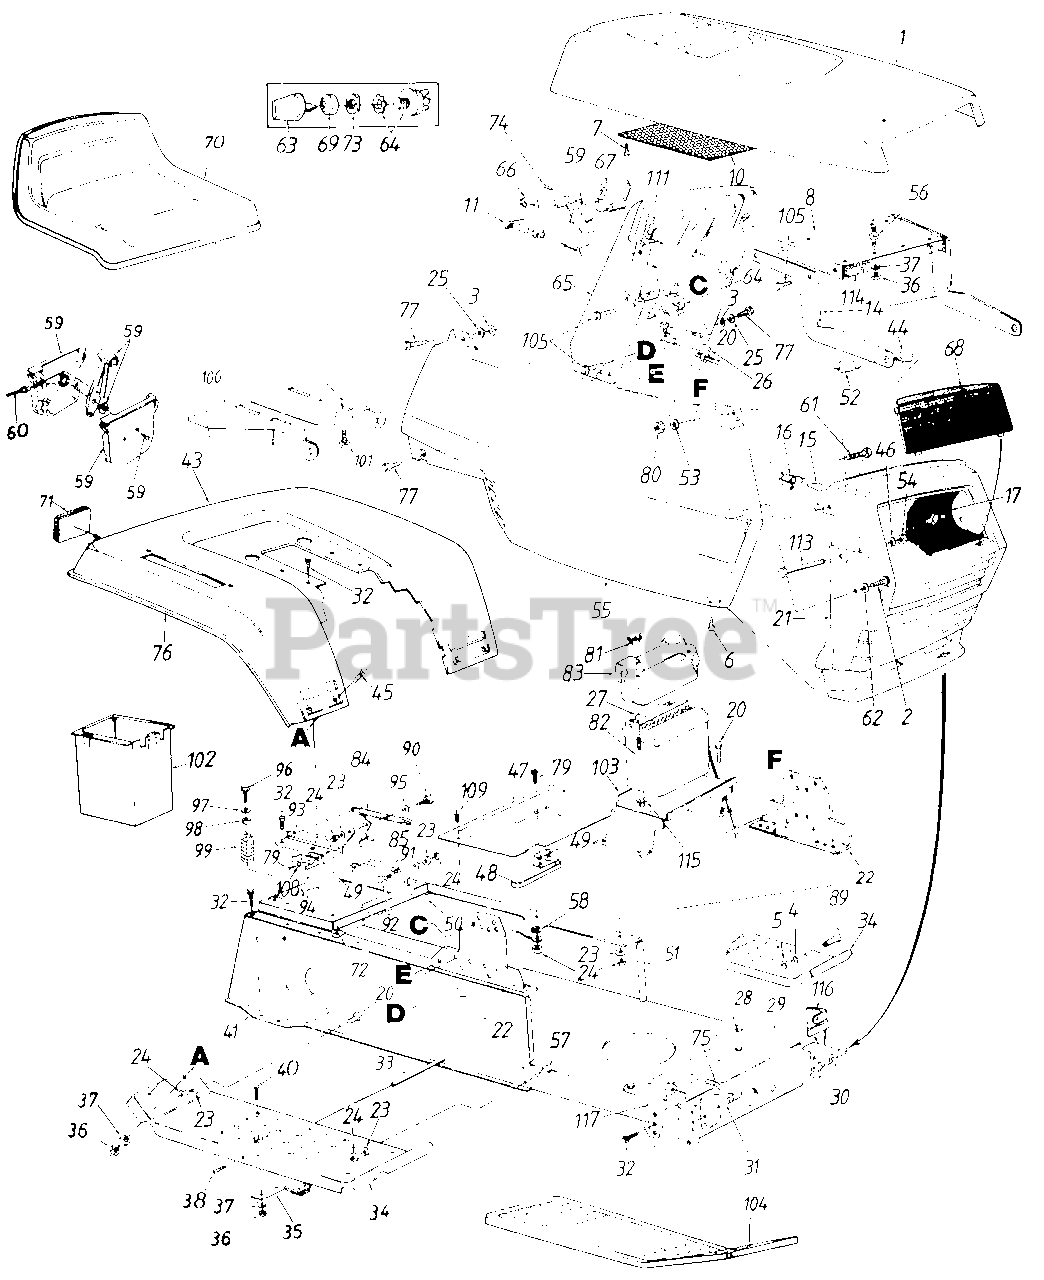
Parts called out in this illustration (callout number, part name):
3	Bolt Retainer 1/4" I.D.
4	L-Wash. 3/8" I.D.
5	Hex Nut 3/8-16 Thd.
6	Truss Mach. AB-Tap Scr. #10 x .5" Lg.
7	Hex Wash Hd. AB-Tap Scr. #8 x .5" Lg.
8	Hood Plate
11	Choke Control 29" Lg.
14	Hood Hinge
15	Lamp
16	Twist Lock-Lamp Socket
17	Reflector-Headlight
20	Hex Bolt 5/16-18 x .75" Lg.
21	Grille
22	Dash Support Bracket
23	L-Wash. 5/16" I.D.
24	Hex Nut 5/16-18 Thd.
25	Fl-Wash. 1/4 I.D. x.93" O.D.
26	Cable Tie
27	12 Volt Battery
28	Lower Frame
29	Front Pivot Brk't.
30	Grille Mount Brk't.-L.H.
31	Grille Mount Brk't.-R.H.
32	Hex Wash. Hd. AB-Tap Scr. 5/16 x .75" Lg.
33	Running Board Rod
34	Running Board
35	Blade Brake Ass'y.
36	Hex Nut 1/4-20 Thd.
37	L-Wash. 1/4" I.D.
38	Truss Mach. Scr. 5/16-18 x .75" Lg.
40	Carr. Bolt 1/4-20 x .62"
45	Carriage Bolt 1/4-20 x .50" Lg.
46	Fl-Wash. .328" I.D. x .68" O.D.
47	Transmission Panel
48	Reverse Safety Switch
49	Insulator Nut Plate
50	Hitch Plate
53	Fl-Wash. .281" I.D. x .5" O.D.
54	Hex Cent. L-Nut 5/16-18 Thd.
55	Side Cover-R.H.
56	Double Ended Stud 1/4-20 Thd.
57	Truss Hd. Scr. 5/16-18 x 1.0" Lg.
58	Ext. L-Wash. 5/16" I.D.
59	Throttle Control Box Ass'y.
60	Throttle Control Wire 18.5" Lg.
61	Hex Bolt 1/4-20 x .62" Lg.
62	Fl-Wash. .281" I.D. x .73" O.D.
64	Ignition Switch
66	Light Switch
67	Ammeter
68	Lens
69	Ignition Switch Cap
70	Seat Ass'y.
71	Reflector
72	Speed Nut #10Z
73	Ignition Switch Nut
74	Truss Mach. AB-Tap Scr. #10 x .5" Lg.
75	Hex AB-Tap Scr. 1/4 x .62" Lg.
76	Trim Strip-81"
77	Hex Wash. Hd. Tap Scr. 1/4 x.75" Lg.
79	Hex Wash. Hd. AB-Tap Scr. #8 x .50" Lg.
80	Hex L-Nut 1/4-20 Thd.
81	Wing Nut 1/4-20 Thd.-Plastic
82	Battery Hold Down Rod
83	Battery Cover
84	Ext. Spring 5.31" Lg.
85	Seat Lift Brkt.
89	Shoulder Bolt
90	Shld. Bolt .437" Dia. x .268"
91	Seat Pivot Brkt. Support-L.H.
92	Shld. Bolt .437" Dia. x .162n
93	Seat Pivot Brkt. Support-R.H.
94	Spring Switch
95	Spr.-Wash. .445" I.D.
96	Hex Wash. Hd. Tap Scr. 5/16-18 x 1n Lg.
97	Fl-Wash. .344" I.D.
99	Compression Spring
100	Seat Pivot Bracket
101	Hex Tap Scr. 3/8-16 x .75"
103	Battery Bracket
104	Foot Pad-L.H.
105	Hex Tap Scr. 1/4-20 x .5" Lg.
108	Fiber Washer
109	Truss Mach. Tap Scr. #10 x .5" Lg.
111	Speed Nut 1/4-20 Thd.
113	Hex Bolt 5/16-18 x 2.75" Lg.
115	Push Nut
116	Muffler Heat Shield Brkt.-L.H.
117	Muffler Heat Shield Brkt.-R.H.
